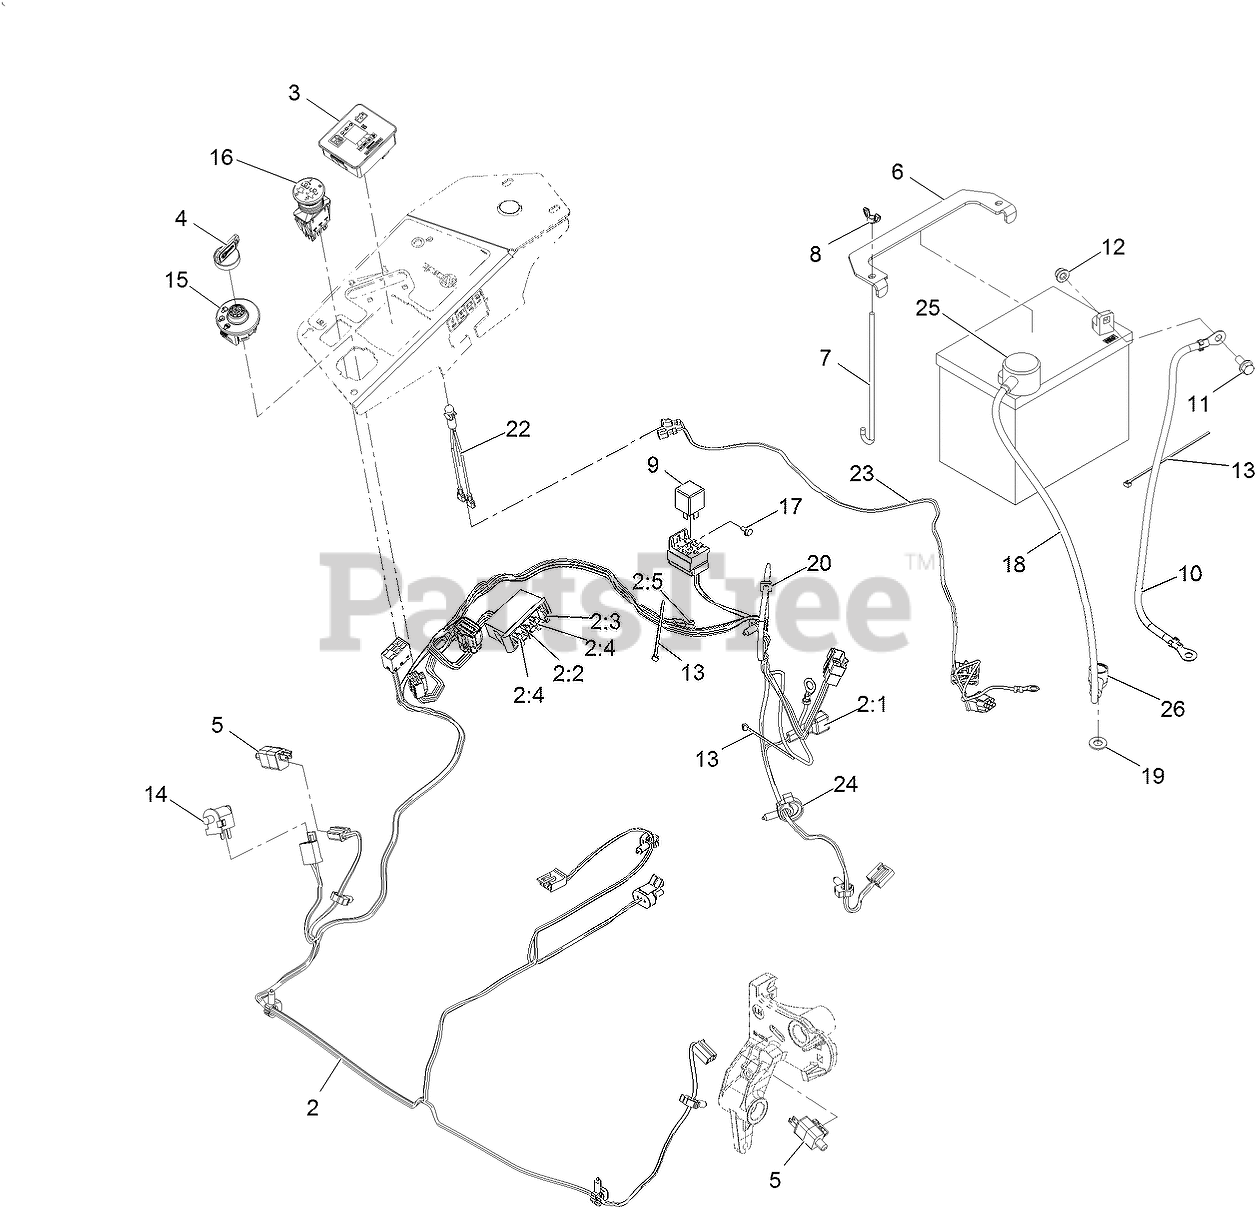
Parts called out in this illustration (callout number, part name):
2	HARNESS-WIRE, MAIN
2:2	FUSE-BLADE, 10 AMP
2:3	FUSE-BLADE, 15 AMP
2:4	FUSE-BLADE, 25 AMP
2:5	CAP-PLUG
3	FUEL/HOUR METER ASM
4	KEYS-IGNITION (SPARE PAIR
4	KEY-IGNITION
6	STRAP-TIE DOWN, BATTERY
7	BOLT-HOLDDOWN
8	WINGNUT
10	CABLE-BATTERY, NEGATIVE
11	SCREW-HHF
12	NUT-HF, NI
13	TIE-CABLE
14	SWITCH-BAIL
15	SWITCH-IGNITION
16	SWITCH-PTO, 10 AMP
17	SCREW-HWH
18	CABLE-BATTERY, POSITIVE
19	WASHER-FLAT
20	TIE-CABLE
22	INDICATOR-LED, RED
23	HARNESS-LIGHT, INDICATOR
24	CLAMP-HOSE
25	INSULATOR-BATTERY
26	INSULATOR-SOLENOID
